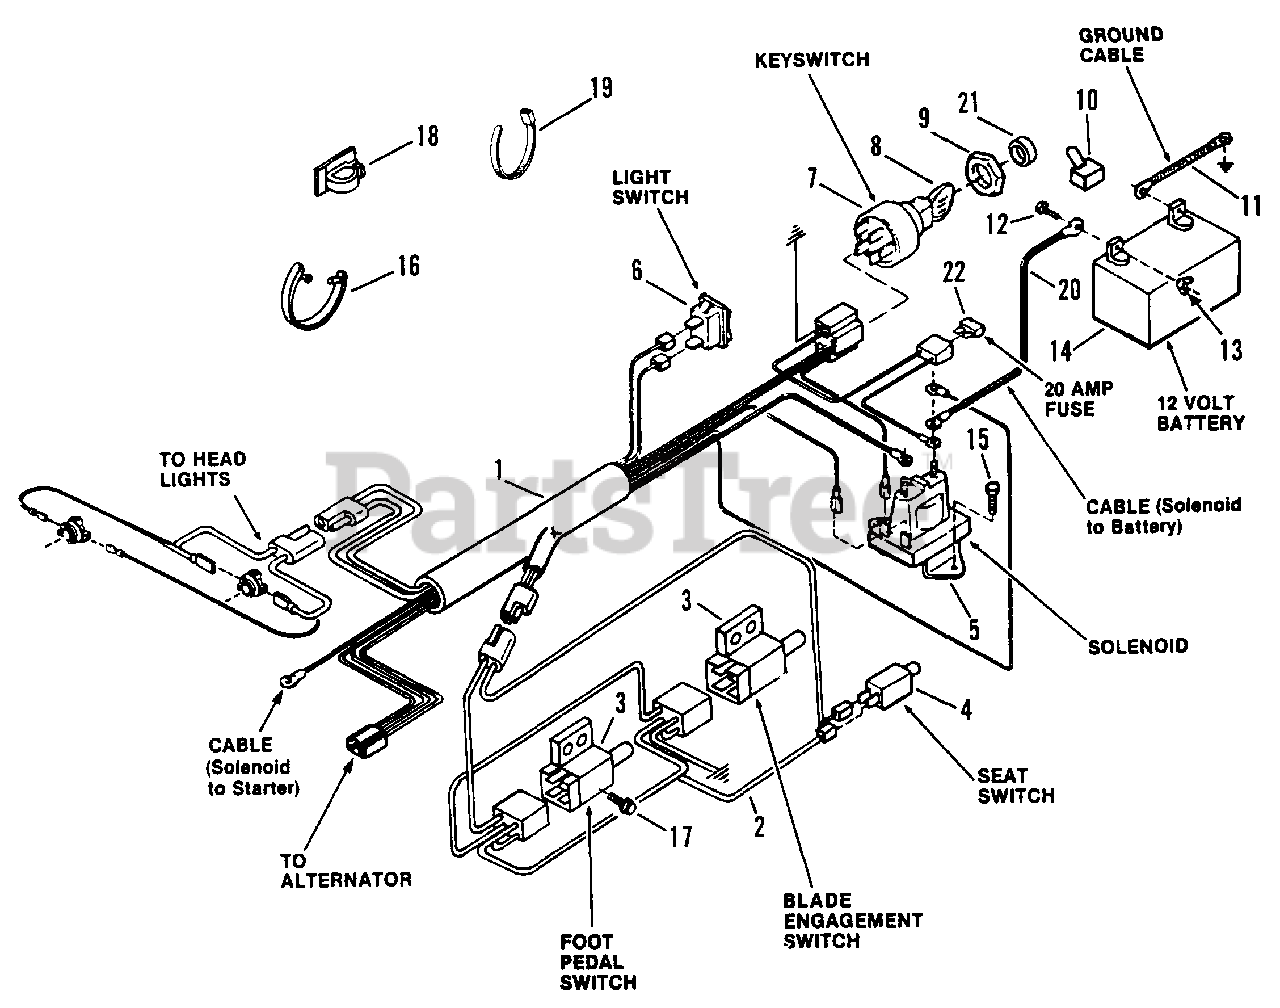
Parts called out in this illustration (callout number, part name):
1	HARNESS, Wiring (KOHLER)
2	HARNESS, Interlock
3	SWITCH, Clutch & PTO
4	SWITCH, Seat NC
5	SOLENOID
6	SWITCH, Light
7	SWITCH, Key
8	KEY, Switch (With Cover)
9	NUT, 5/8-32 Hex
10	COVER, Positive Terminal
11	CABLE, Negative 15" 8 AWG Black
12	BOLT, 1/4-20x3/4 Carriage
13	WING NUT, 1/4-20
14	KIT, Battery
15	SCREW, 1/4-20x1/2" Self-Tapping
16	TIE, Wire
17	SCREW, #10-24 x 1/2" Hex Washer Self-Tap (Torx)
18	CLIP
19	TIE, Cable 7"
20	CABLE, Positive 11" 8 AWG Red
21	BEZEL
22	FUSE, 20 Amp
